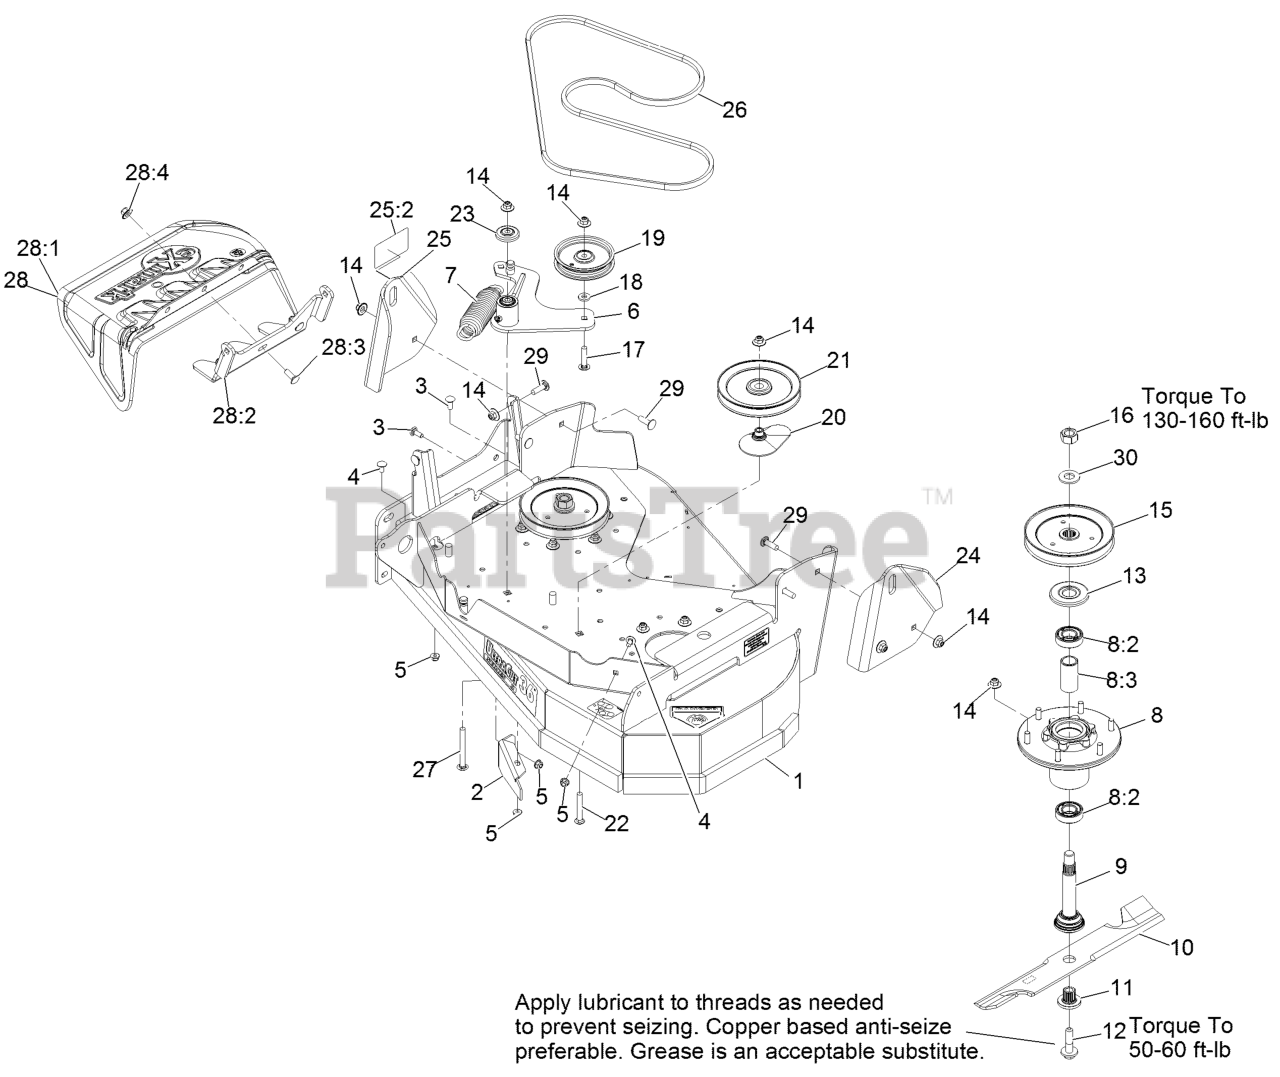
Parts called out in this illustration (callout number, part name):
1	DECK ASM - 36
2	BAFFLE-DOGLEG
3	SCREW-CARR
4	SCREW-CARR
5	NUT-HF, NI
6	IDLER ARM ASM -
7	SPRING-EXTENSION
8	ASM-CUTTER HSG WITH BEARINGS
8:2	BEARING-BALL
8:3	SPACER-BEARING
9	ASM-SPINDLE AND SEAL
11	BUSHING,SPLINED
12	SCREW,SEMS 1/2-20 X 2.19
13	GUARD,BEARING TOP .989
14	Nut-Nyloc 3/8-16 Flg
15	SHEAVE,BLADE DRIVE 6.50
16	NUT-HEX
17	SCREW-CARR
19	PULLEY-IDLER
20	SPACER-PULLEY
21	PULLEY-IDLER
22	SCREW-CARR
23	GUARD-TOP
24	PUSH-TOWER,LH 36
25	PUSH TOWER-RH 36, W/DECAL
25:2	DECAL-WARNING, DISCHARGE
26	BELT-V
27	BOLT-SHOULDER, CARRIAGE 3/8-16 X 3 1/2
28	CHUTE - DISCHARGE ASM
28:1	CHUTE,DISCHARGE
28:2	BRACKET-CHUTE, DISCHARGE
28:3	SCREW-CARR
28:4	Nut-Nyloc 3/8-16 Flg
29	Bolt-Carriage 3/8-16 X 1 1/4
